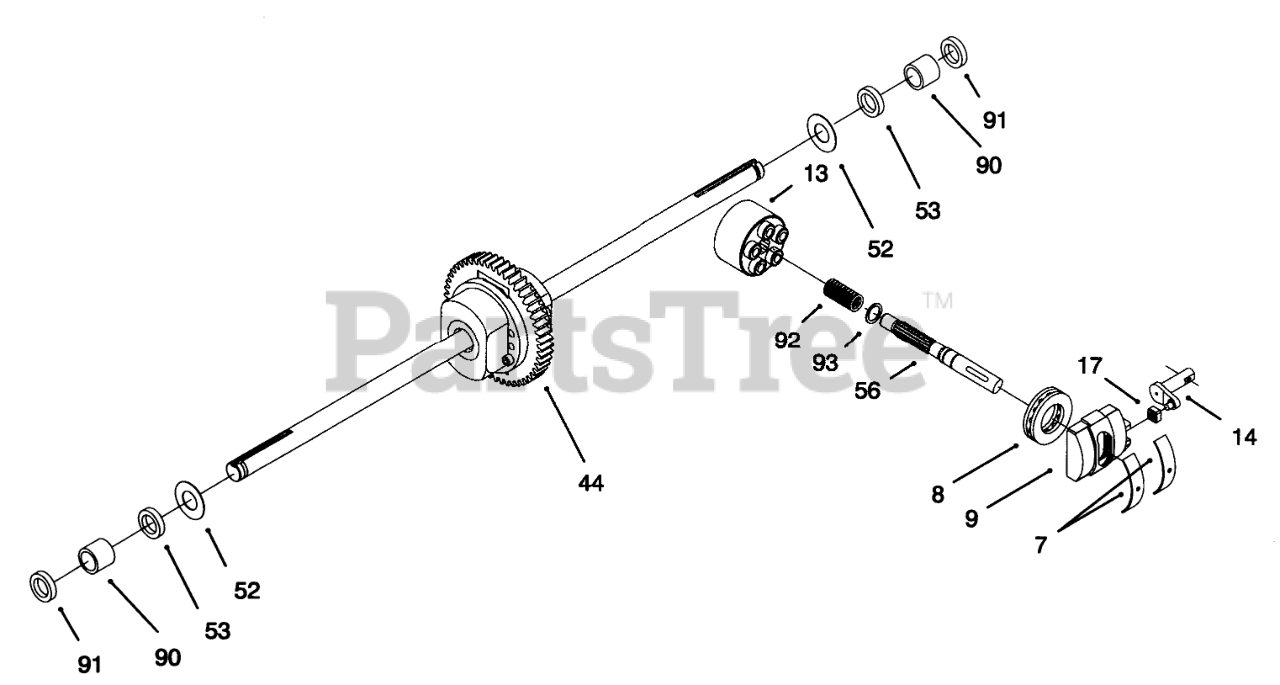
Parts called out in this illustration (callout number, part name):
7	BEARING-CRADLE
8	BEARING - THRUST
9	SWASHPLATE-VARIABLE
13	BLOCK - CYCLINDER ASM
14	ARM-TRUNION
15	SEAL-LIP
17	GUIDE-SLOT
24	SEAL-LIP
44	ASM - DIFFERENTIAL
52	WASHER
53	SEAL
56	SHAFT - INPUT
90	SLEEVE - BEARING
91	SEAL - WIPER
92	SPRING-BLOCK
93	WASHER-THRUST
